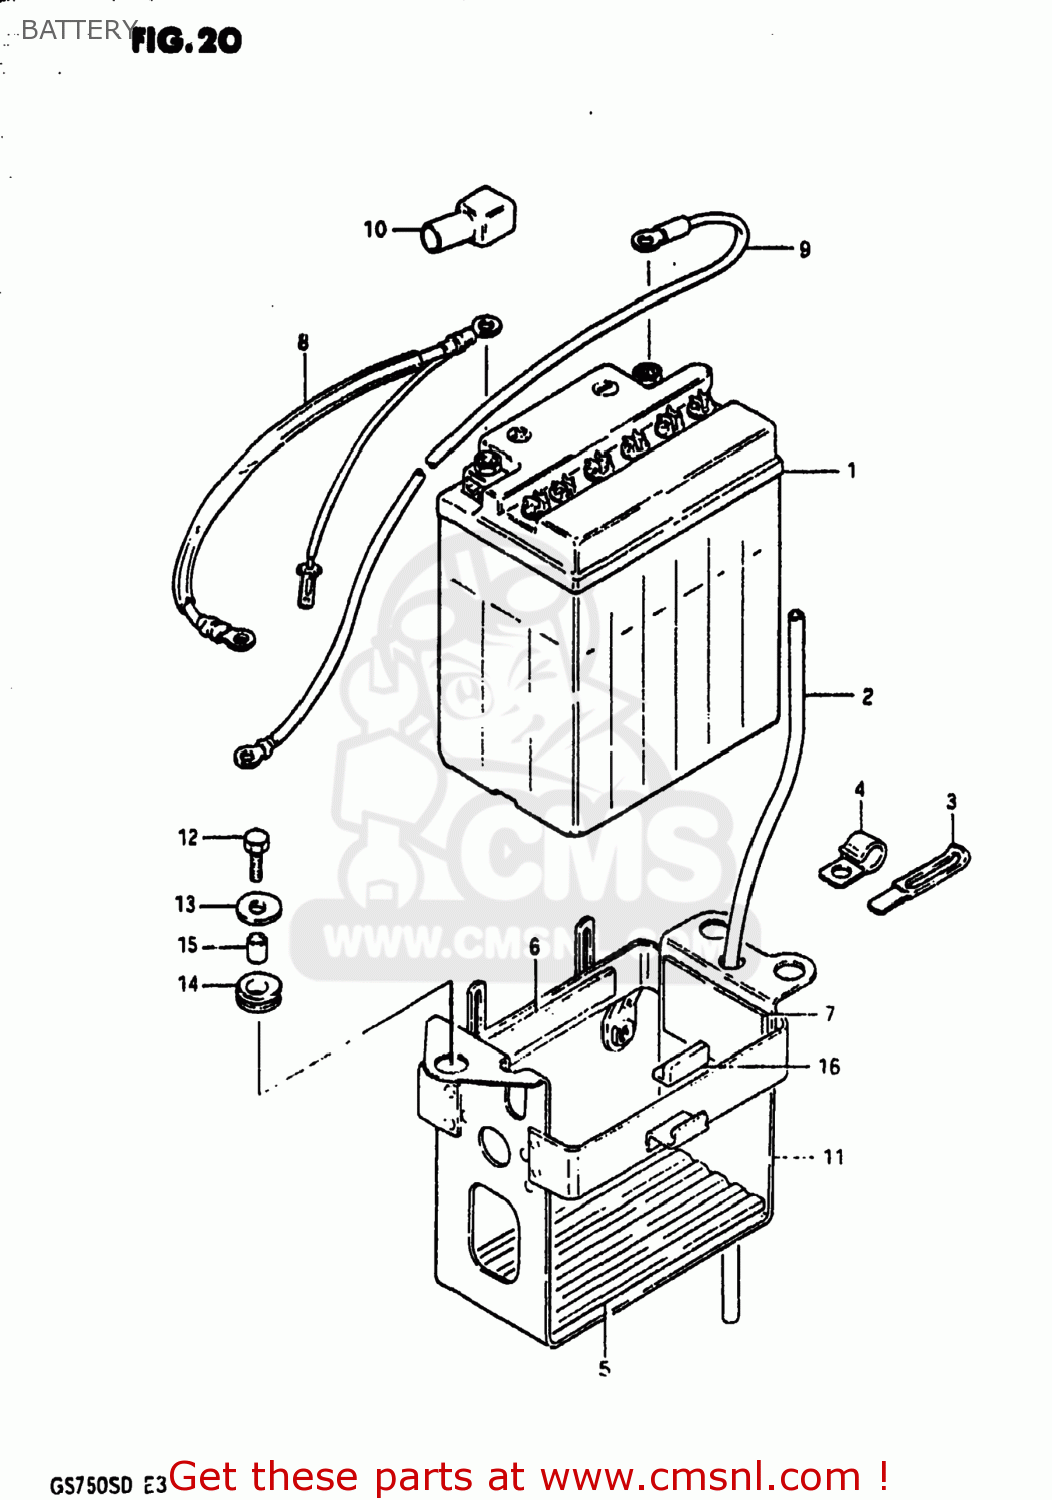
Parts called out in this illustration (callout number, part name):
1	BATTERY ASSY (12V)
2	HOSE,BATTERY EXHAUST
3	CLAMP L:35
4	CLAMP
5	PROTECTOR,BATTERY
6	PROTECTOR(20X90)X4
7	PROTECTOR(170X95X3.0)
8	WIRE,BATTERY PLUS
9	LEAD WIRE,BATTERY(-)
10	CAP,TERMINAL
11	HOLDER,BATTERY
12	BOLT, UPPER
13	WASHER
14	CUSHION
15	SPACER(6.1X9X7.5)
16	CUSHION,FRAME COVER
